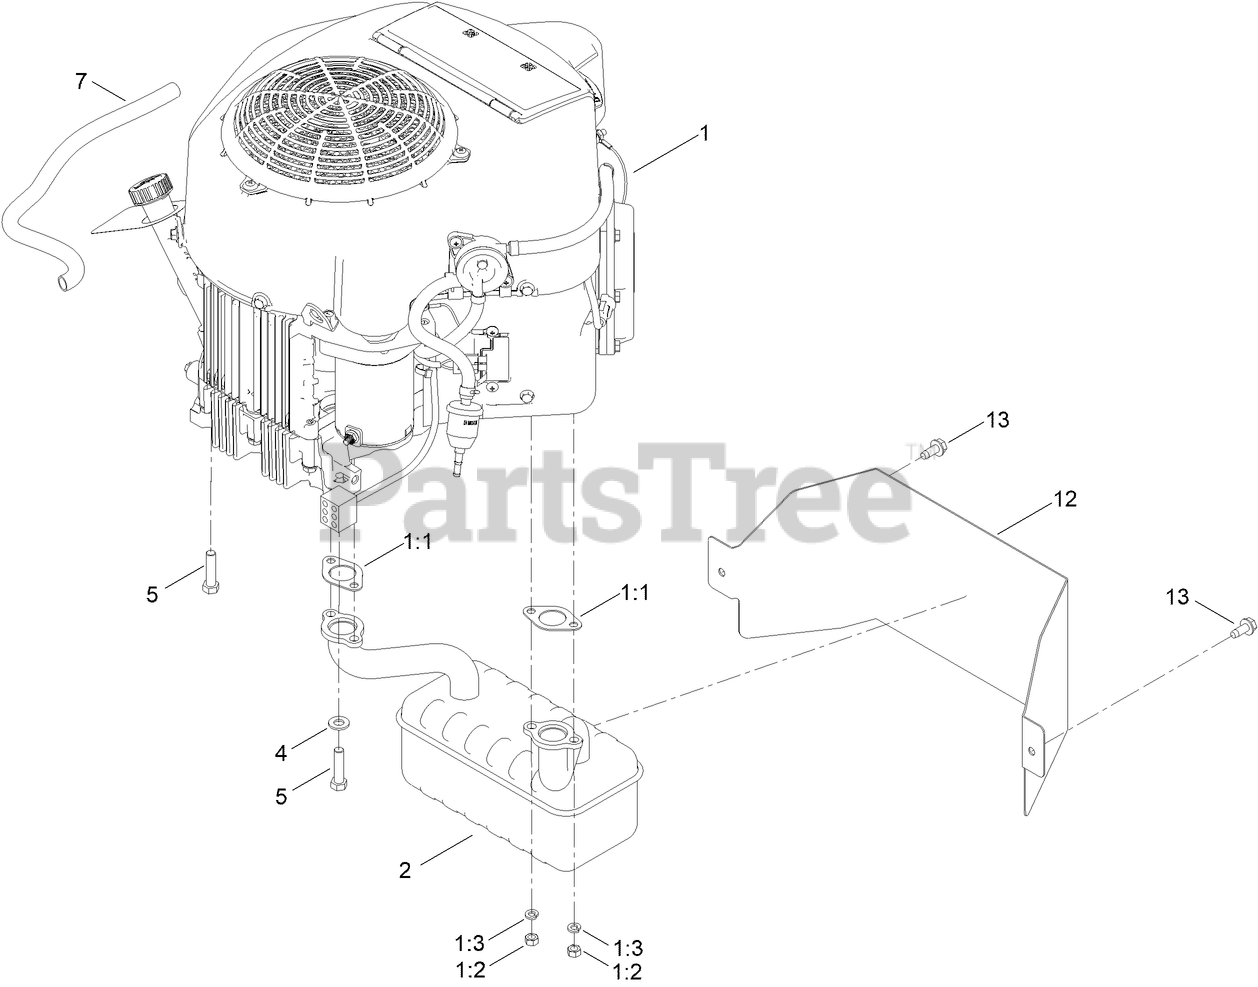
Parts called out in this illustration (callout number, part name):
1:1	GASKET-EXHAUST
1:3	WASHER-LOCK
2	MUFFLER
4	WASHER-FLAT
5	BOLT-HH
7	TUBE-DRAIN, OIL
12	HEAT SHIELD - MUFFLER
13	SCREW-HWHTF
